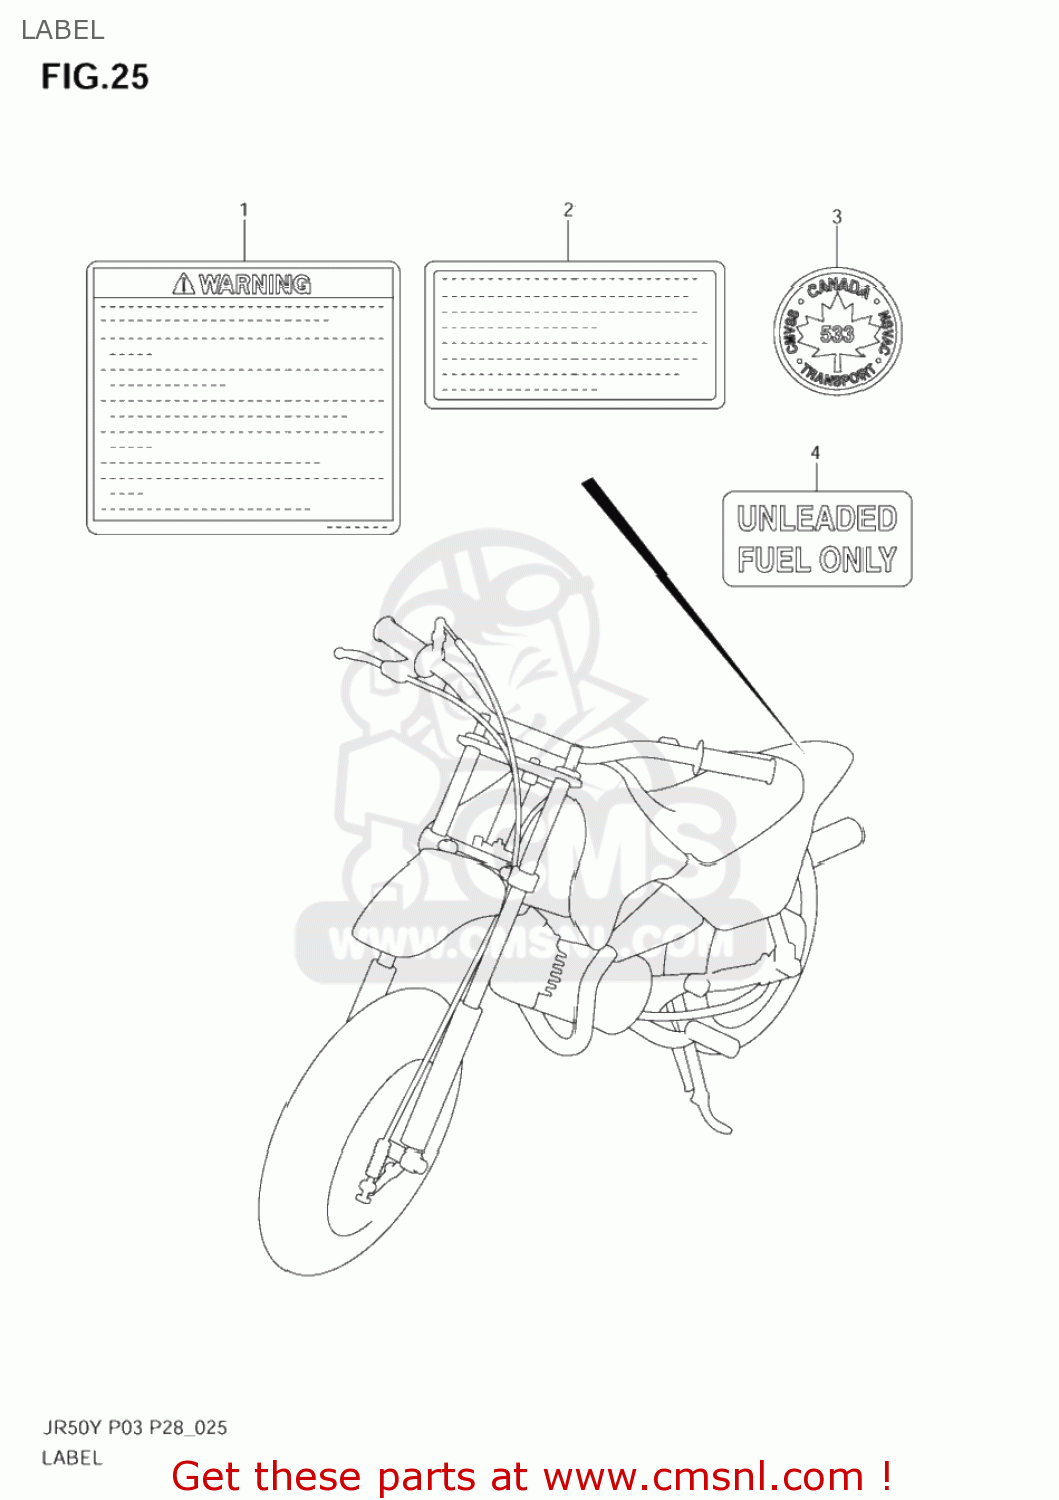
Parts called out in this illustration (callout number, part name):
1	LABEL,GENERAL WARNING
2	LABEL,MANUAL NOTICE
3	PLATE
4	LABEL,UNLEADED FUEL
5	MANUAL,OWNER'S
